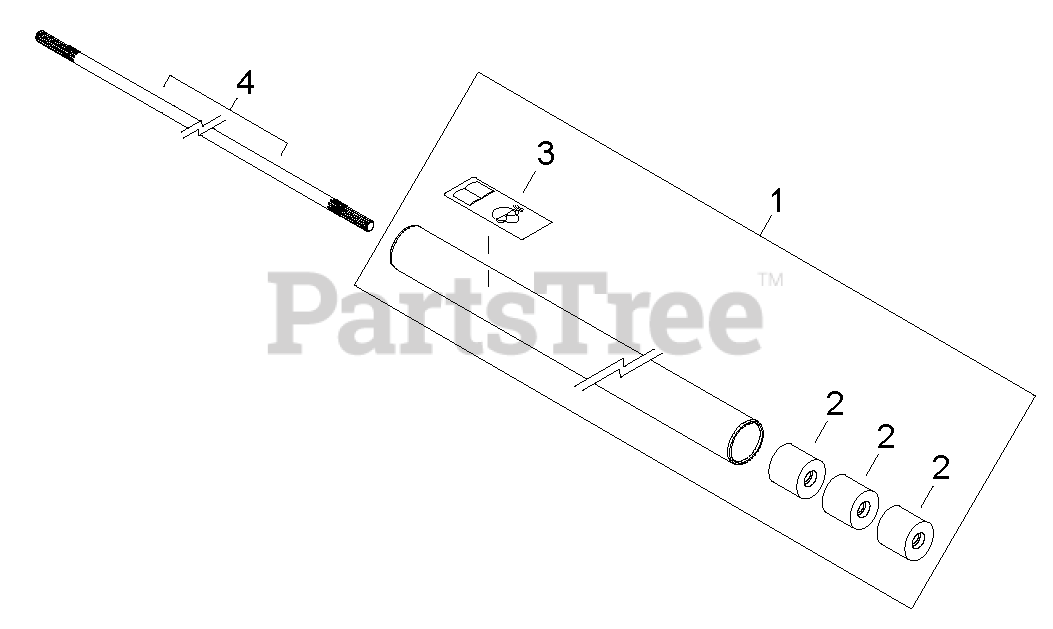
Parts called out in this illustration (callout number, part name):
2	BUSHING
3	LABEL, CAUTION
4	MAINSHAFT Ø6×790 MM
9-1	MAIN PIPE ASSY
